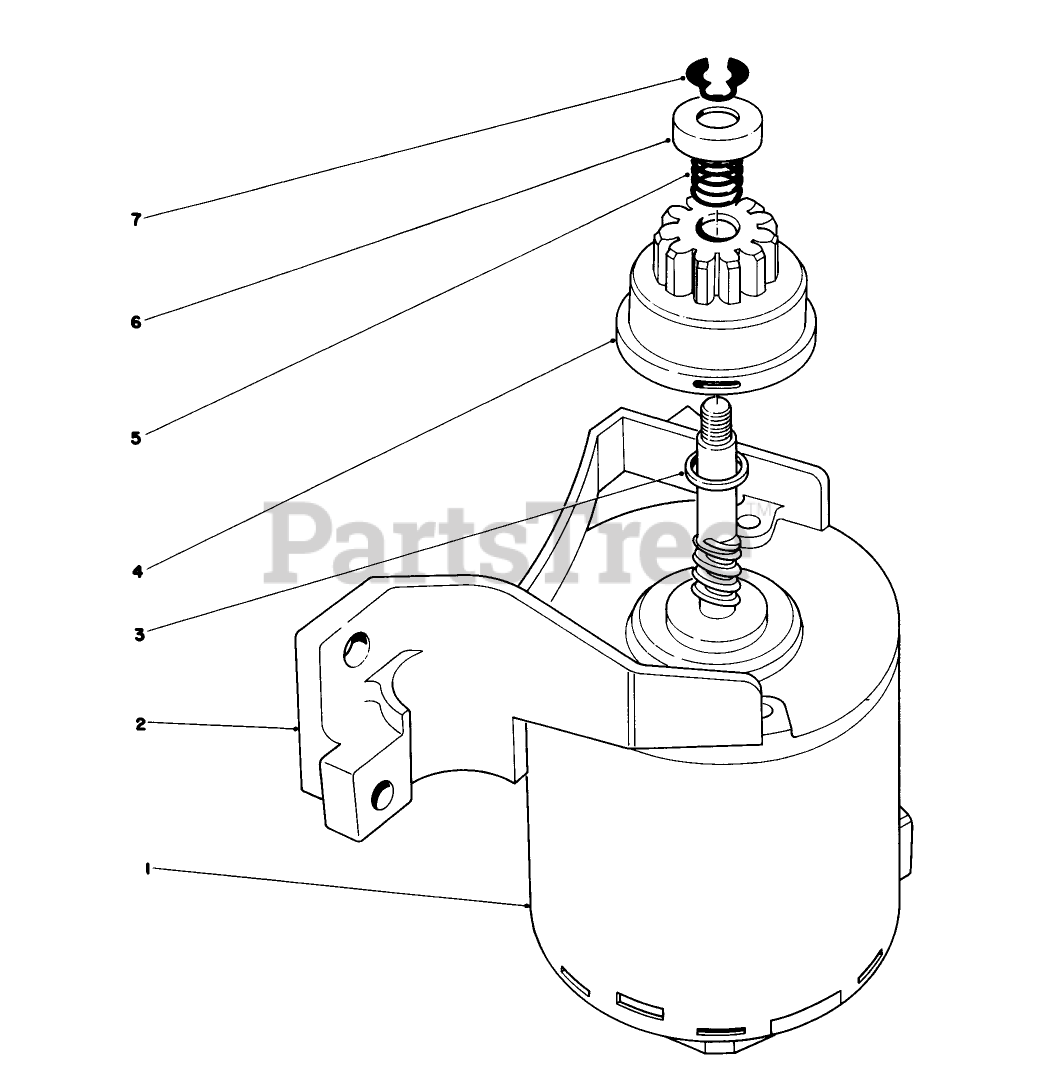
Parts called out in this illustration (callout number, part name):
1	END FRAME W/BRUSH
2	BRKT END FRAME
3	SPACER
4	PINION ASM
5	COMPRESSION SPRING
6	PINION STOP
7	RING-RETAINING
